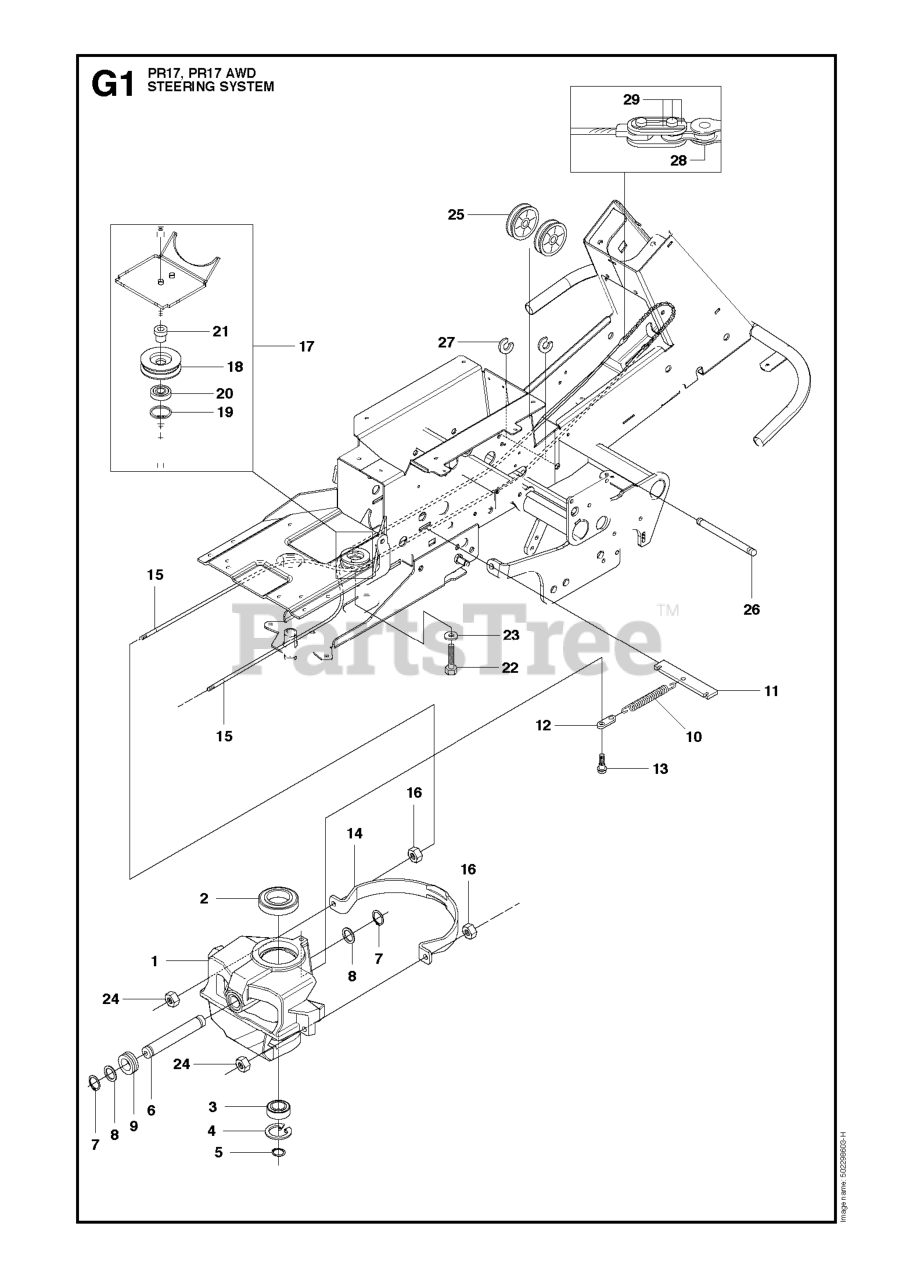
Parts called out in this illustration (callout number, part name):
2	BALL BEARING 6010 2RS1
3	Ball Bearing 6005-2rs
4	CIRCLIP SGH 47
5	RETAINING RING SGA 25
7	RETAINING RING SGA 25
11	SPRING BRACKET
14	WIRE GUIDE
15	RP STEERING CABLE COMPLETE
16	NUT
19	CIRCLIP SGH 47
20	BALL-BEARING 6204-2RS
22	REPL BY 725 25 00-71
24	NUT
26	SHAFT
27	RETAINING RING
28	STEERING CHAIN
